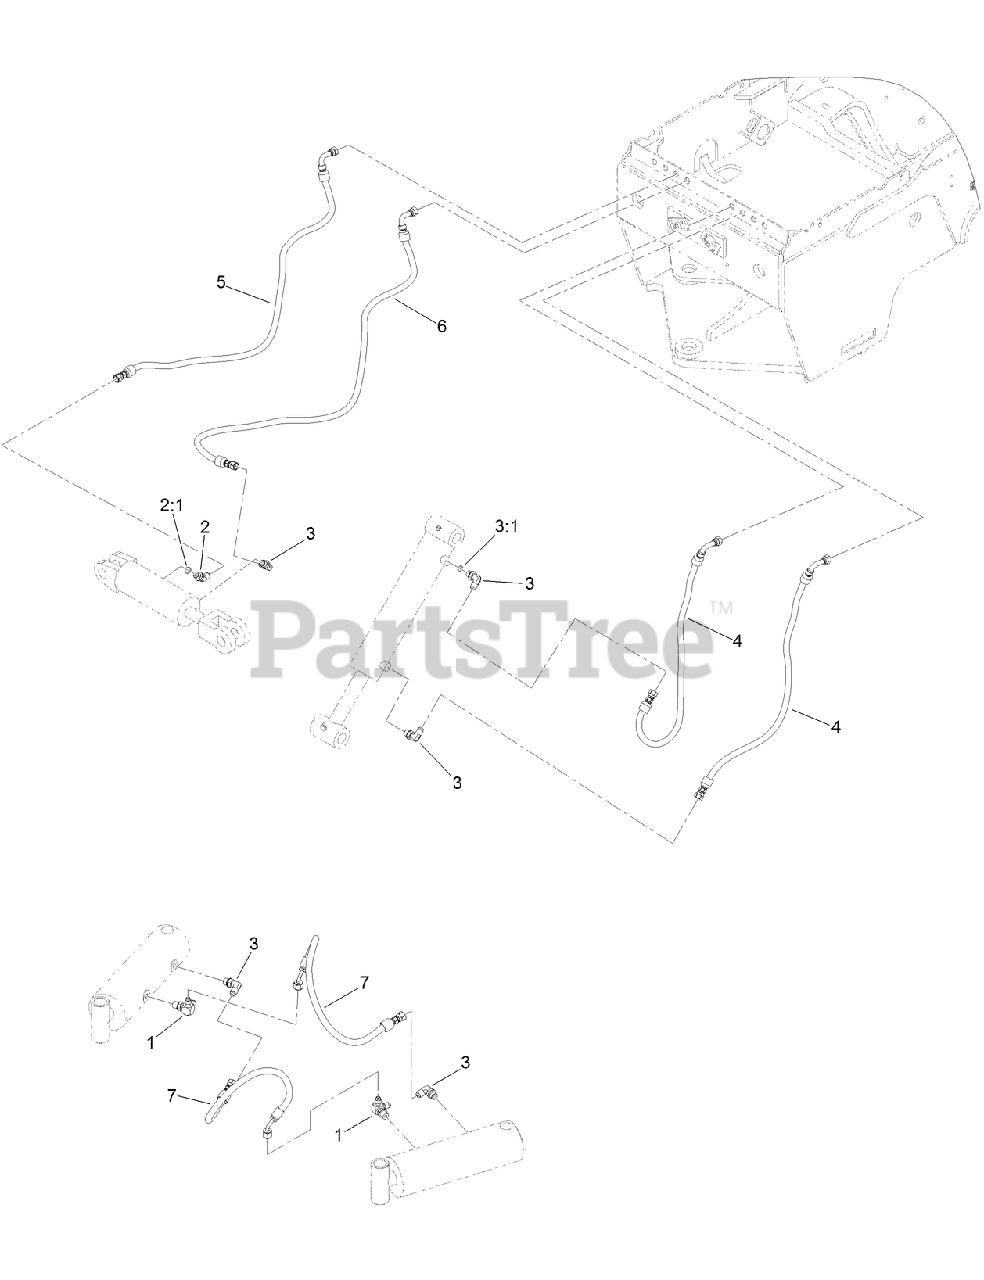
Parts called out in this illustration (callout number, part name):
1	FITTING
2	FITTING-ELBOW, 45 DEG
2:1	O-RING
3:1	O-RING
4	HOSE ASM-HYD HP
5	HOSE ASM-HYD HP
6	HOSE ASM-HYD HP
7	HOSE ASM
